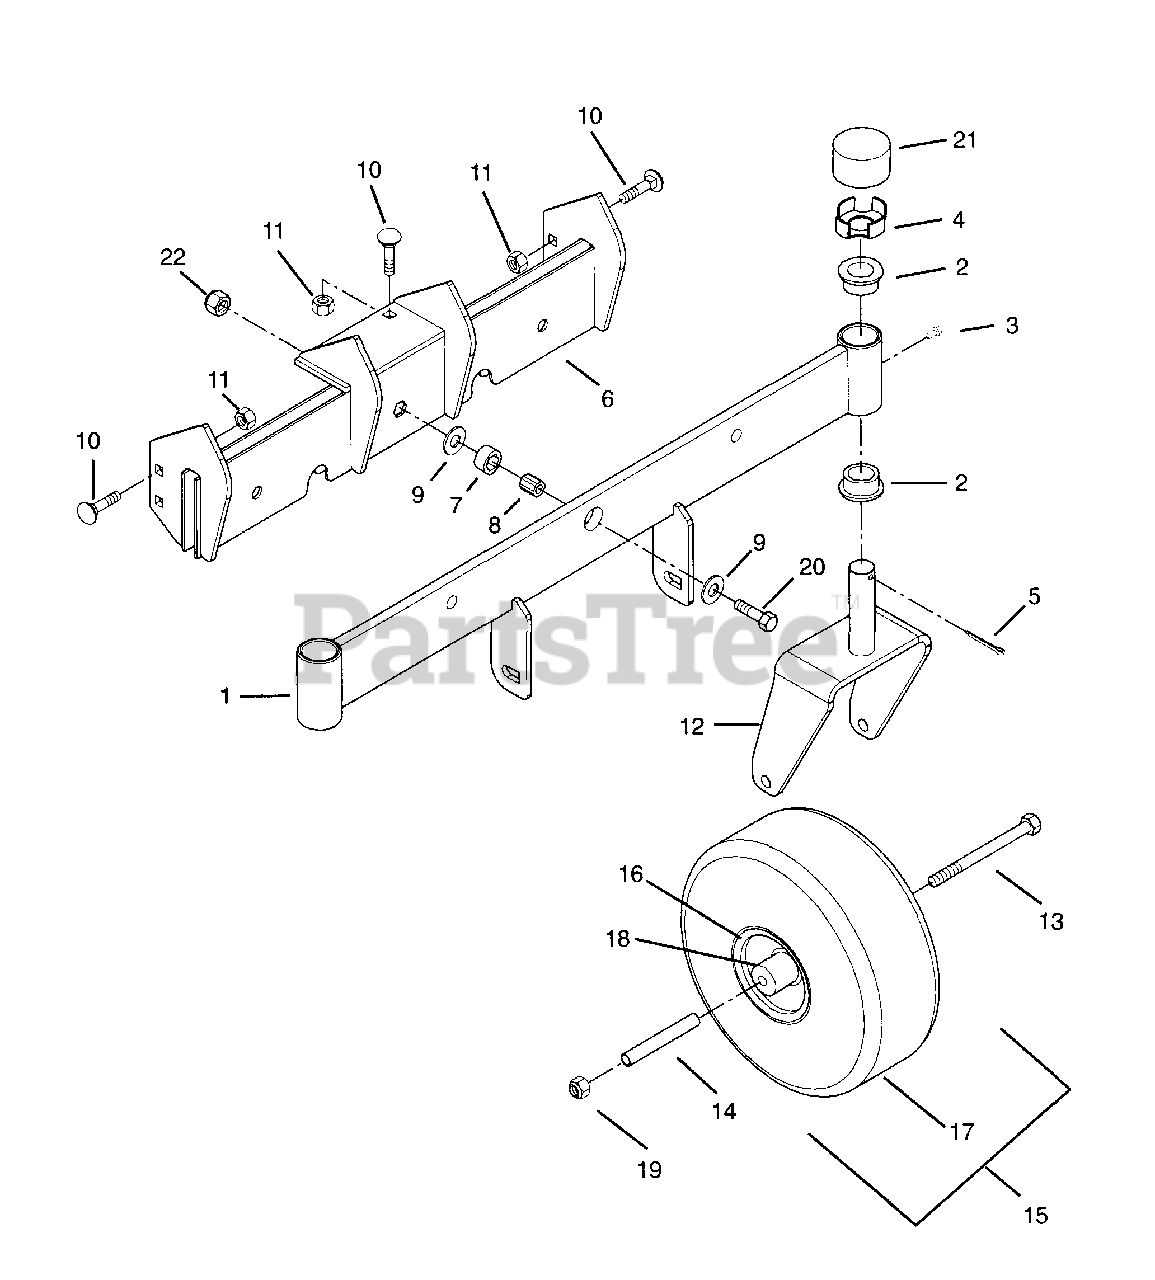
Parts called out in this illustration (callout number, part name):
1	AXLE WELDMENT
2	BSHG-FLG1.020X1.385X.75X1.75NY
3	FTG-LUBE .25-28X.256 YWZC
4	SPINDLE CUP
5	PIN-COTR .188X1.50
6	AXLE FRAME WELDMENT
7	BSHG-SLV .626X1.000X.524 HEX
8	BSHG-SLV .377X.623X.775 HEX
9	WSHR-FL-STL .380X1.50X.125 PL
10	BLT-RDHDSQNK .375-16X.75 GR5PL
11	NUT-LK-CTR .375-16 GR A PL
12	WLDT,CASTER FORK
13	BLT-HEX .50-13X6.50
14	BUSH.,CASTER FORK
15	T/WHL 11X4.00-5 RIBBED
16	RIM ASSY 11X4.00-5
17	TIRE RIBBED 11X4.00-5
18	RIM BEARING-11X4.00-5 RIM
19	NUT-LK-NYL .50-13 GR 5 PL
20	BLT-HEX .38-16X1.75 PL GR5
21	HUB CAP
22	NUT-LK-NYL .375-16 PL
